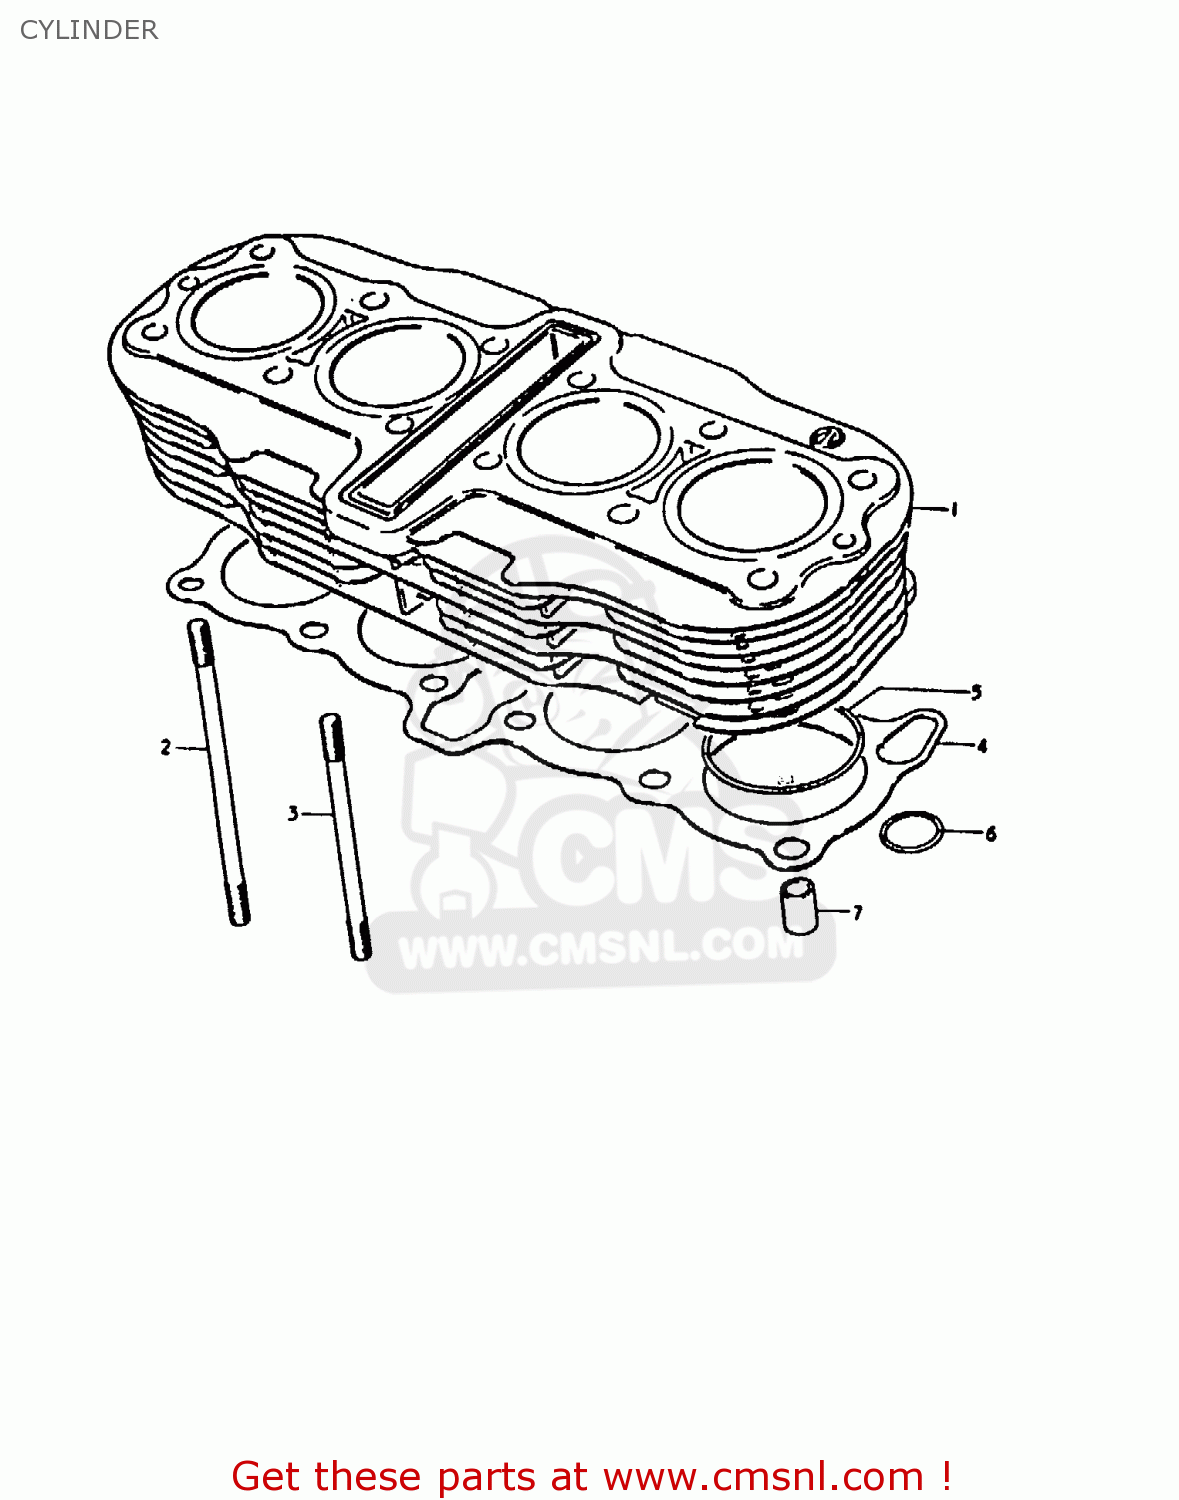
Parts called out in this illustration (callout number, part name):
1	CYLINDER
2	BOLT,STUD
3	STUD
4	GASKET,CYLINDER (MCA)
5	O RING(D:2,ID:74)
6	O RING(D:3.05)
7	PIN
